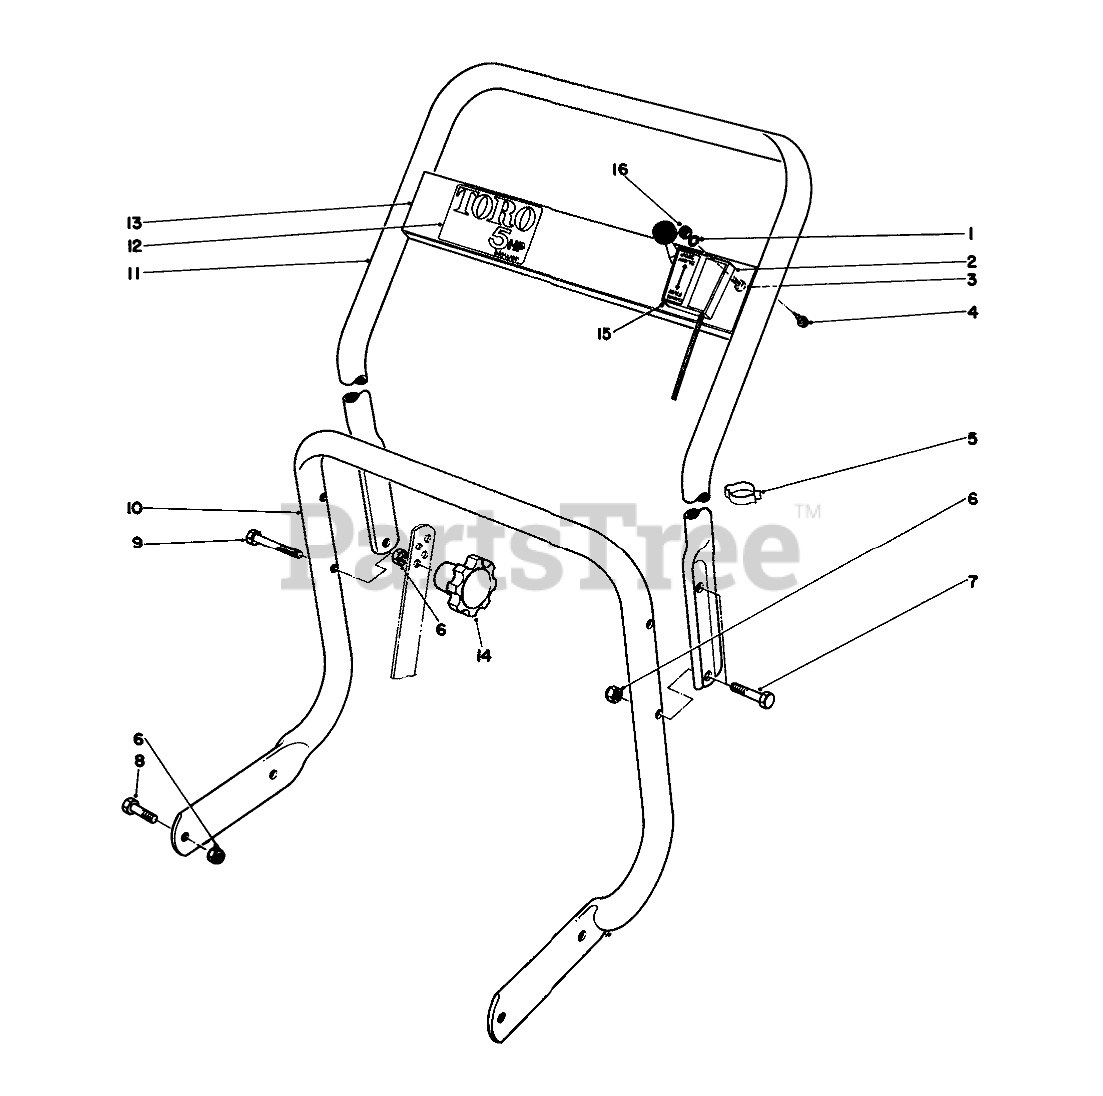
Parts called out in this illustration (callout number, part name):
1	WASHER-LOCK
2	Throttle Control (Incl . Ref. #15)
3	8-32 X 1/2 RND HD MS
4	SCREW-HWHTF
5	BODEN CLIP
6	NUT-LOCK, CONE
7	SCREW-HH
8	SCREW-HH
9	SCREW-HH
10	HANDLE
11	UPPER HANDLE
12	ESCUT PLATE DECAL
13	BLOWER ESCUTCHEON PLT
15	Cover-Throttle Control
16	NUT-HEX
